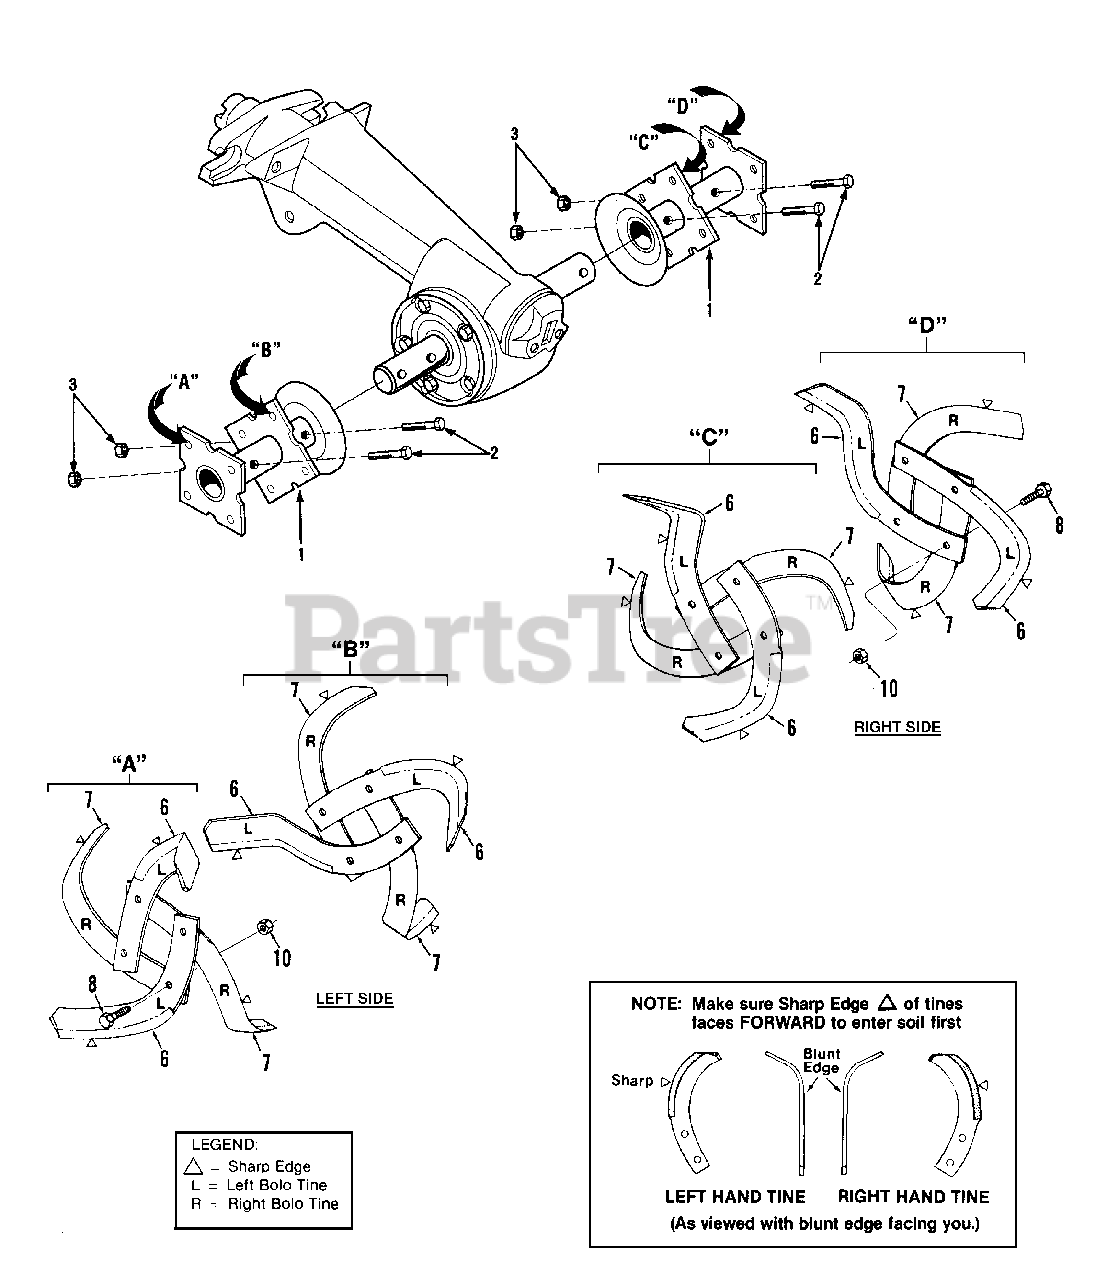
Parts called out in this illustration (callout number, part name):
1	Tine Holder-welded steel, fits left or right sides
2	Bolt-hex hd., 3/8-16 x 2"
6	Bolo Tine-single, left hand.
7	Bolo Tine-single, right hand.
8	Bolt-hex hd., 3/8-16 x 1"
10	Locknut-hex, 3/8"-16
